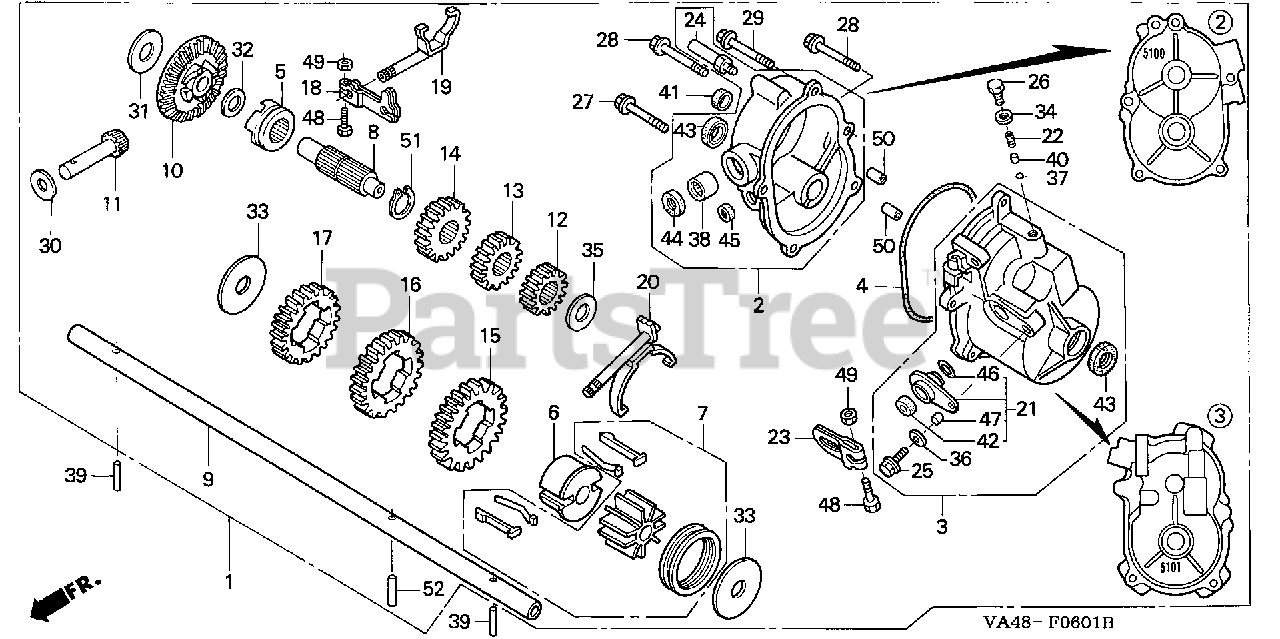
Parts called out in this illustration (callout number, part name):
1	TRANSMISSION ASSY. (DANA CORP.)
2	CASE ASSY., R. TRANSMISSION
3	CASE ASSY., L. TRANSMISSION (NOT AVAILABLE)
4	O-RING, TRANSMISSION CASE
5	CLUTCH, DRIVEN
6	BOSS, CHANGE SHAFT
7	KEY & HOLDER ASSY.
8	COUNTERSHAFT
9	SHAFT, FINAL
10	GEAR, BEVEL (44T)
10	GEAR, BEVEL
11	PINION, BEVEL
12	GEAR, FIRST DRIVE (14T)
13	GEAR, SECOND DRIVE (18T)
14	GEAR, THIRD DRIVE (20T)
15	GEAR, FIRST DRIVEN (33T)
16	GEAR, SECOND DRIVEN (29T)
17	GEAR, THIRD DRIVEN (27T)
18	ARM, CLUTCH
19	SHAFT, SHIFT
20	FORK, SHIFT
21	GUIDE ASSY., CHANGE LEVER
22	SPRING, BALL SET
23	ARM, CHANGE
24	BOLT, GUIDE (8MM)
25	BOLT, FLANGE (6X16)
26	BOLT, HEX. (8X10)
27	BOLT, FLANGE (6X35)
28	BOLT, FLANGE (6X25)
29	BOLT, FLANGE (6X25)
30	WASHER (10X21)
31	WASHER, THRUST (14X32X1)
32	WASHER (14MM)
33	WASHER, THRUST (15X45)
34	WASHER, SEALING (8X16X1.6)
35	WASHER B, THRUST (12MM)
36	WASHER, PLAIN (6.5X15)
37	BALL, STEEL (6)
37	BALL, STEEL (#6) (3/16)
38	BEARING, NEEDLE (10X17X20)
39	ROLLER (5X23.8)
40	RETAINER, BALL (6MM)
41	PLUG, SEALING (14X4)
42	OIL SEAL (8X16X6)
43	OIL SEAL (15X24X5)
44	OIL SEAL (10X17X4)
45	OIL SEAL (8X14X5)
46	O-RING (12.3X1.9)
47	COLLAR, FAN
48	BOLT, HEX. (5X20)
49	NUT, HEX. (5MM)
50	PIN A, DOWEL (8X14)
51	CIRCLIP (OUTER) (18MM)
52	ROLLER (6X22.4)
